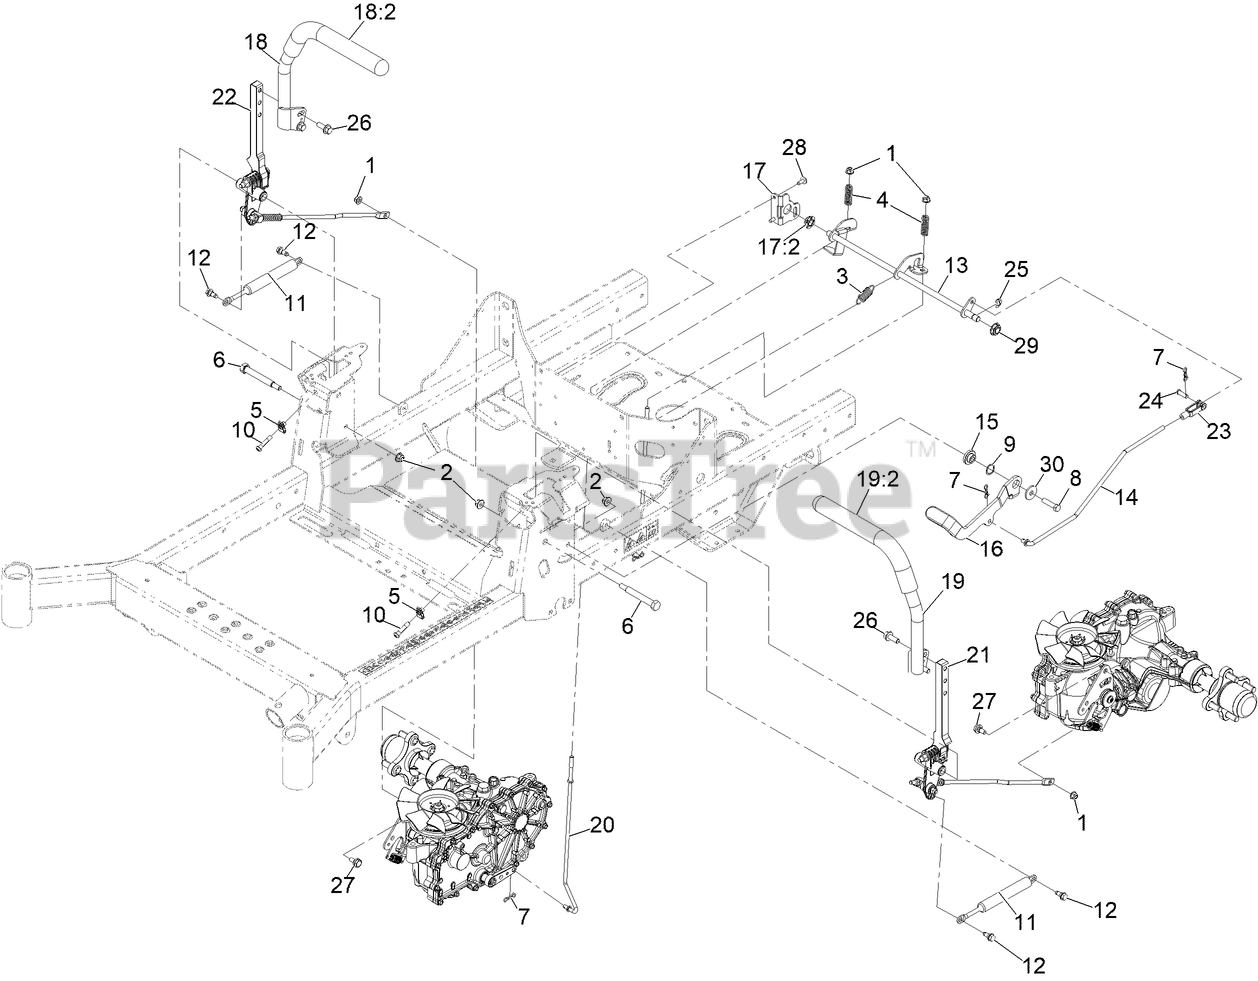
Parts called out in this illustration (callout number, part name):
1	NUT-HF, NI
2	NUT-HF, NI
3	SPRING-EXTENSION
4	SPRING-COMPRESSION
6	BOLT-PIVOT
7	PIN-COTTER, LOCKING
8	SCREW-HH
9	WASHER-WAVE
10	SCREW-HSBH
12	SCREW-SHOULDER
13	SHAFT-BRAKE
14	LINKAGE-BRAKE, UPPER
15	PIVOT-FLANGE
16	LEVER-BRAKE (WITH GRIP)
17	BRACKET-BRAKE
17:2	BEARING-SPHERICAL
18	ASM, MOTION CONTROL W/ GRIP, RT
19	ASM, MOTION CONTROL W/ GRIP, LT
20	LINKAGE-BRAKE, LOWER
21	ASM, MOTION CONTROL LT
22	ASM, MOTION CONTROL RT
23	YOKE-ADJUSTABLE
24	PIN-CLEVIS
25	RING-RETAINING, EXTERNAL
26	SCREW-HHF
27	BOLT-SHOULDER,HFH
28	SCREW-TORX
29	BEARING-SPHERICAL
30	WASHER
